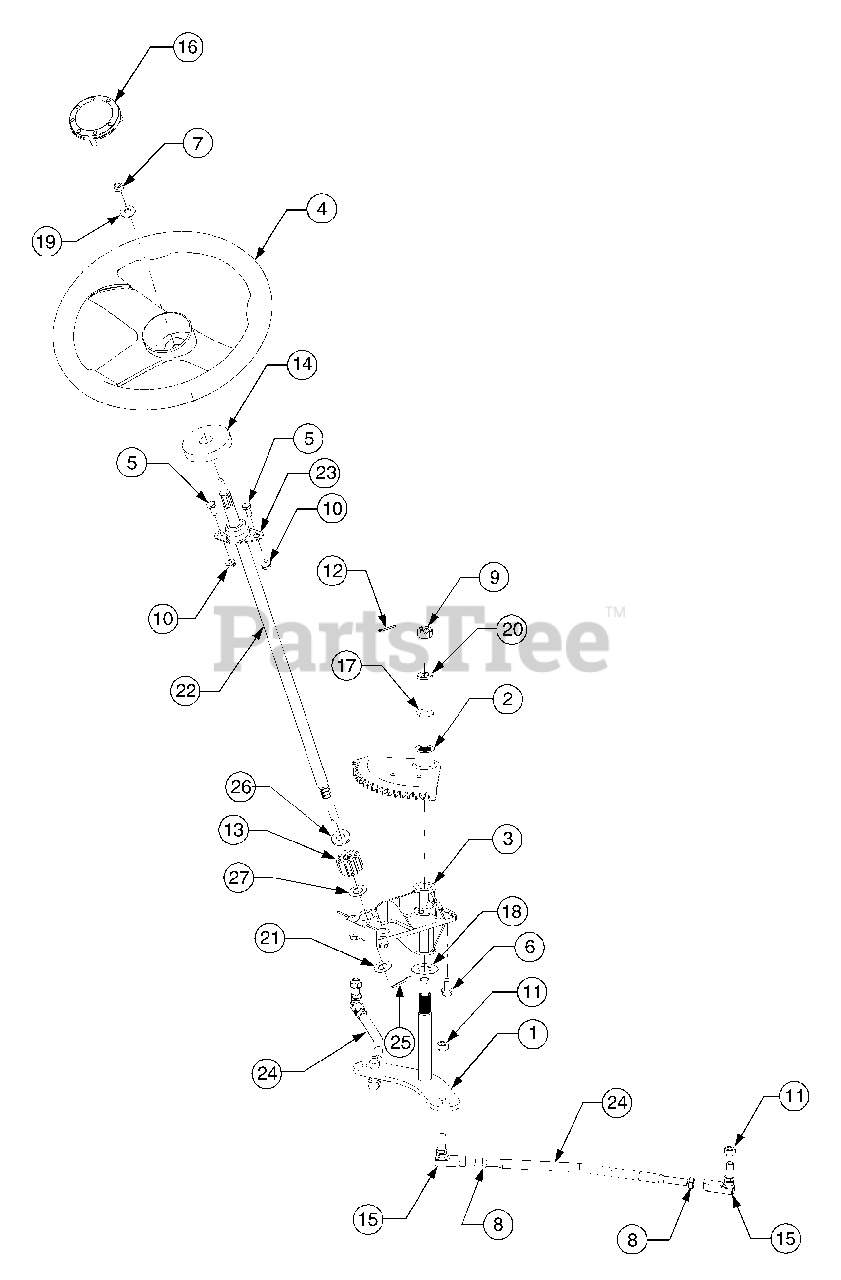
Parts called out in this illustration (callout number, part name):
1	Arm Assy, Lower Steering
2	Segment Assy, 18T Steering
3	Housing Assy,
4	Wheel, Steering, Soft Grip
5	Screw, Hex Cap, 5/16 - 18 x .75, GR5
6	Screw, Hex Wash. Hd. Tapp 5/16 - 18 x .75
7	Nut, Hex Center Lock, 5/16-18
8	Nut, Hex Jam, 3/8-24 GR2
9	Nut, Hex Slotted, 1/2-20 GR5
10	Nut, Hex Flange Lock, 5/16-18 GR5
11	Nut, Hex Lock, 3/8-24 GR5
12	Pin, Cotter, 3/32 Dia x 1.25
13	Pinion, Steering
14	Gasket, Steering
15	Joint, Ball, 3/8-24
16	Cap, Steering Wheel
17	Washer, Flat, .510 x 1 x .06 Thk
18	Washer, Flat, .760 x 1.5 x .03 Thk
19	Washer, Bell., .34 x .872 x .061 Thk
20	Washer, Lock, 1/2
21	Washer, Flat, .531 x 1 x .027 Thk
22	Shaft, Steering
23	Bearing, Flange
25	Pin, Cotter, 1/8 x 1.0
26	Washer, Flat, .56 x 1.0 x .04 Ht
27	Washer, Flat, 1.12 x .5 x .125
